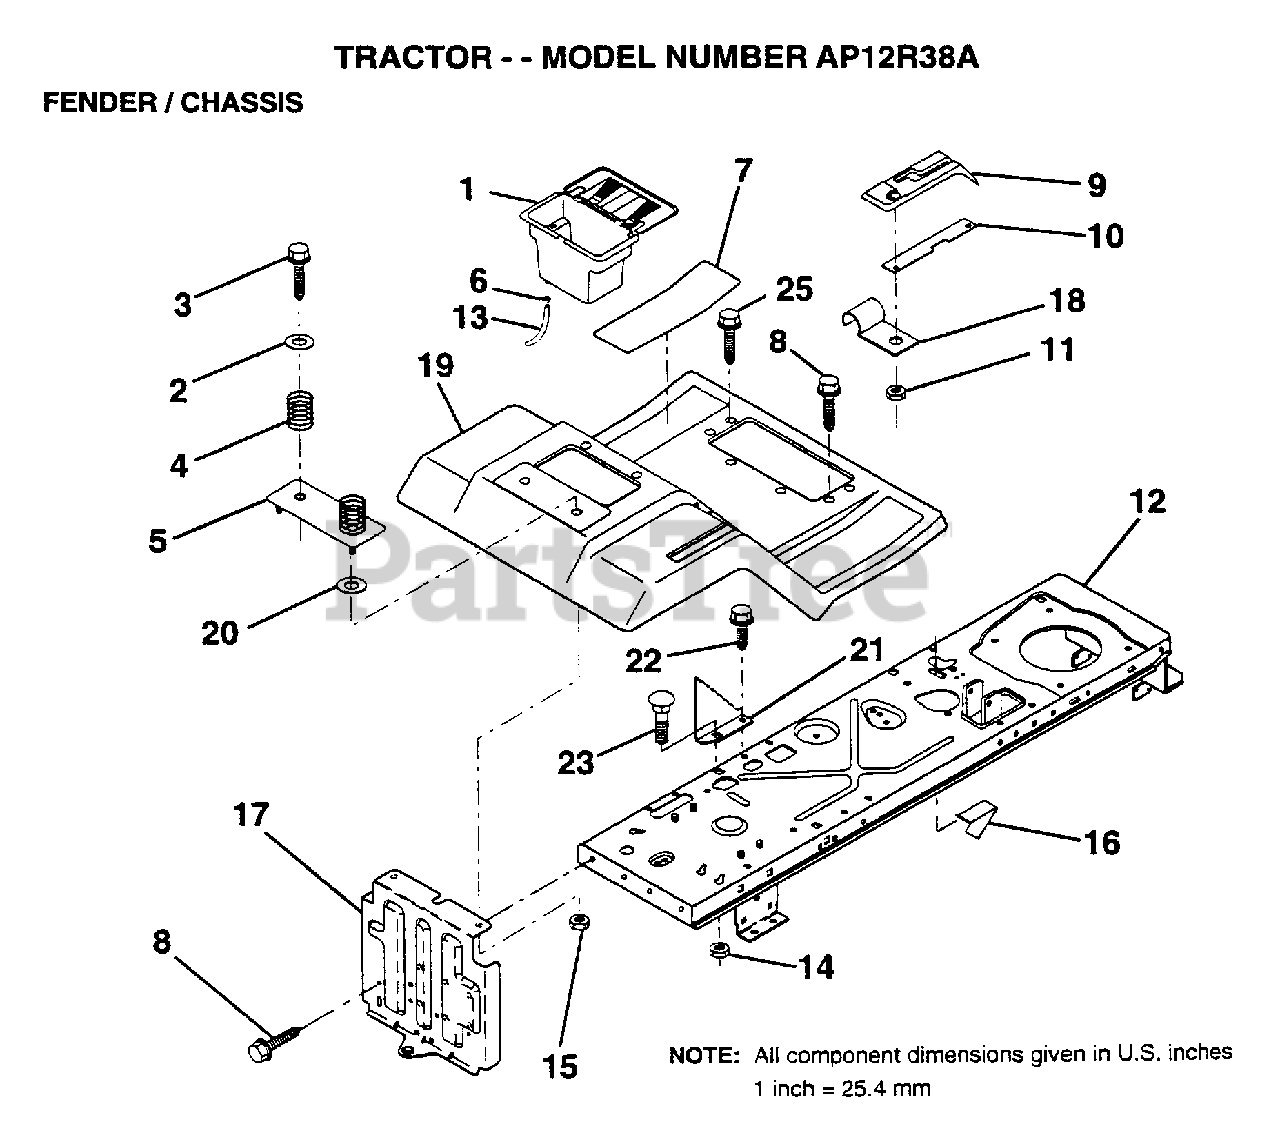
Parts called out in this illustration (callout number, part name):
2	WASHER
3	SCREW
4	SPRING COMPRESSIO
5	BTRY FENDER PLATE
6	HOSE CLAMP T
7	PAD FOOTREST
8	SCREW
10	PLATE LOCK SHIFT
11	NUT
12	CHASSIS.WELD.ASM.
13	TUBE T
15	NUT HXKEP 1/4X20
17	DRAWBAR ASM LR
18	"CLIP,INSULATOR"
19	FENDER/FOOT MS505
21	BRACKET STOP DEPT
22	SCREW LT
25	SCREW TI
